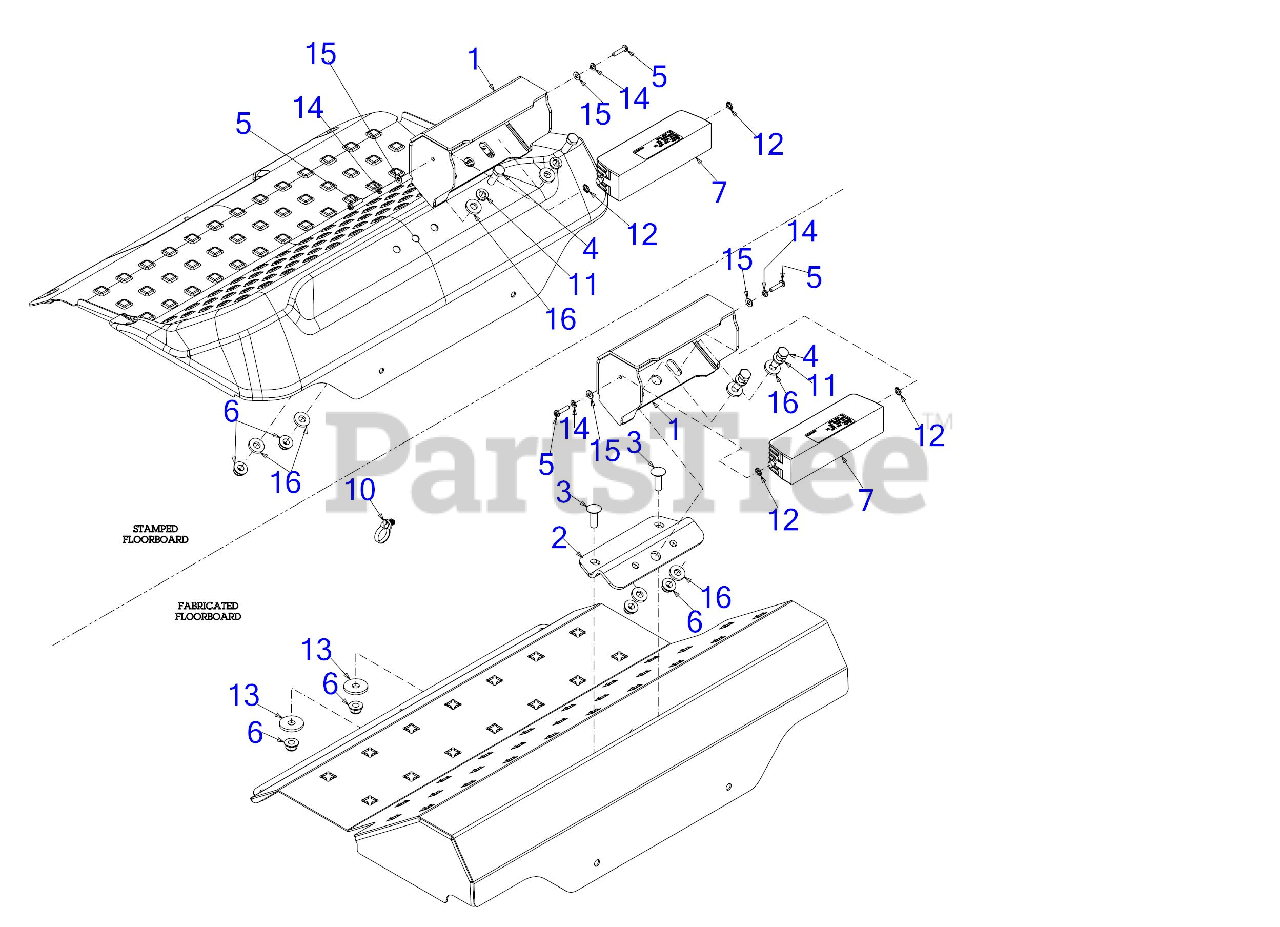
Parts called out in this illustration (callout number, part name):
3	CARRIAGE BOLT 5/16-18 x 1.00
4	SCREW 5/16-18 x 1.0 GR5
5	SCREW #8-32 x .750
6	FLANGE LOCK NUT 5/16-18
7	HEADLIGHT ASSEMBLY
10	CABLE TIE
11	LOCK WASHER 5/16
12	LOCK WASHER
13	FLAT WASHER
14	LOCK WASHER
15	FLAT WASHER .203 ID x .41 OD x .040
16	FLAT WASHER
